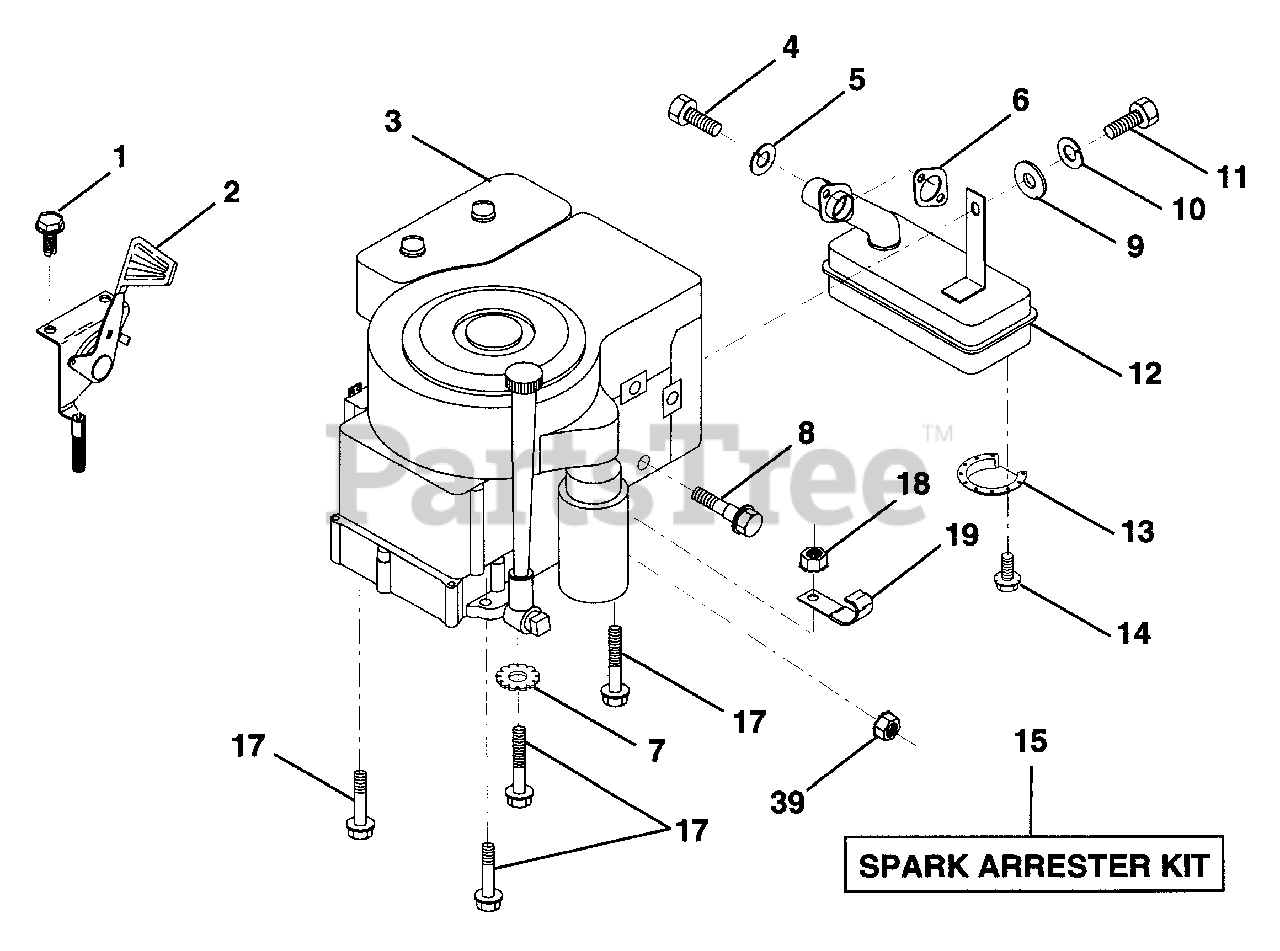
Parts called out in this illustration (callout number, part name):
1	Screw, Hex Head, Thread Cutting 1/4-20 x 1/2
2	Control, Throttle
4	Screw, Hex Cap Hd. 5/16-18 x 3/4
5	Washer, Lock, Heavy Helical Spring 5/16
6	Gasket, Exhaust
7	Washer, Lock Ext. Tooth 3/8
8	Bolt, Shoulder 5/16
9	Washer 5/16 x 3/4 x 16 Gauge
10	Washer, Lock, Heavy Helical Spring 1/4
11	Bolt, Hex, Fin.
13	Deflector, Muffler
14	Screw, Spider lock Hex Hd 8 x 1/2
15	Arrester, Spark
17	Screw, Hex Washer Head, Thd., Roll. 3/8-16 x 1-1/2
18	Nut, Hex, Keps 3/8-16
19	Clip, Fuel Line
30	Nut, Keps Hex 1/4-20
